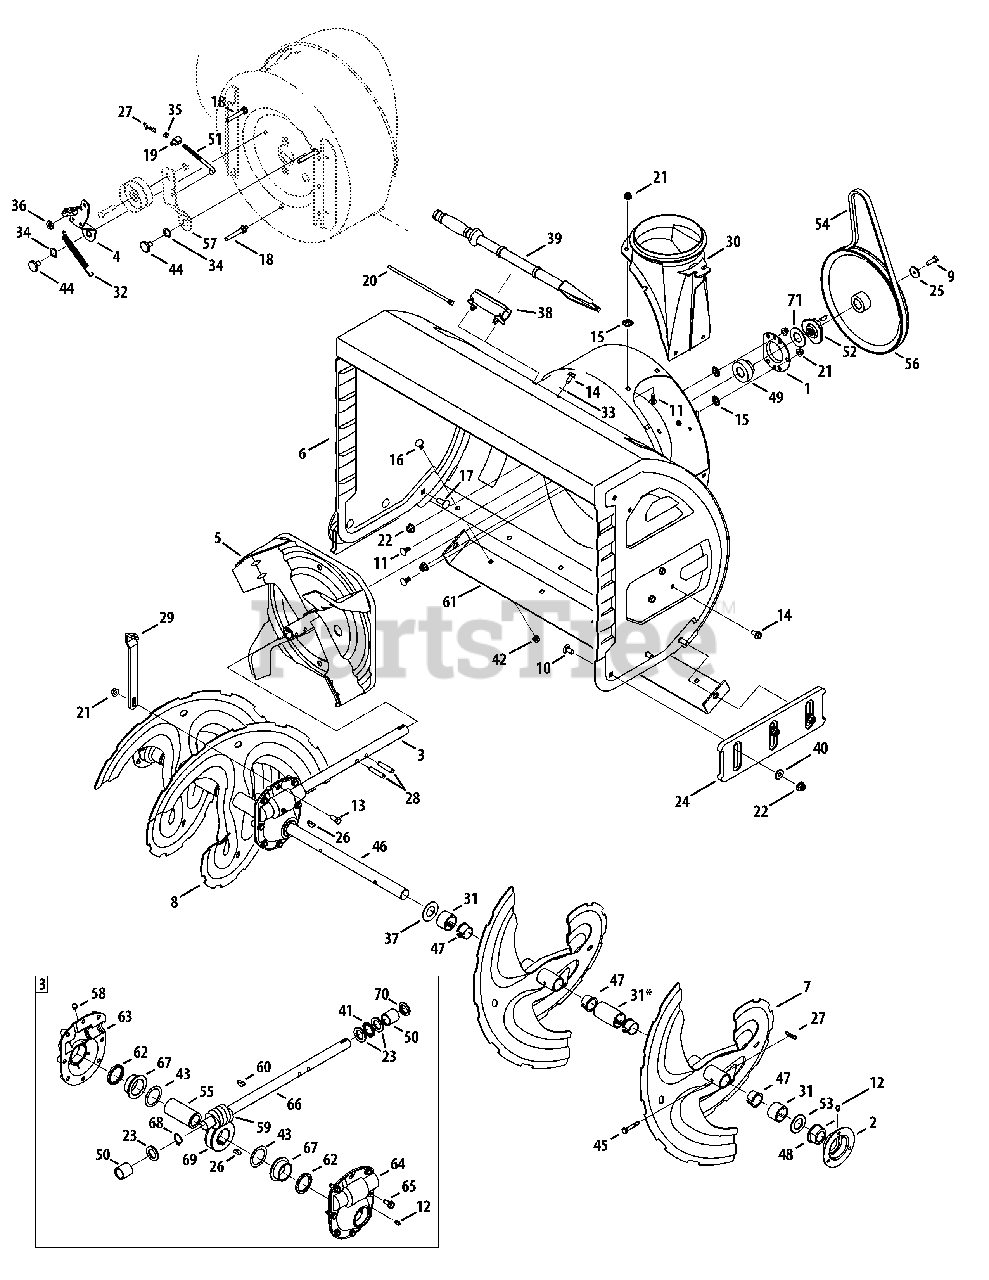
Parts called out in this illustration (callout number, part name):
1	Housing, Bearing
2	Housing, Bearing
3	Gear Box Assembly
4	Bracket Assembly, Auger Brake
5	Impeller, 16"
6	Housing, Auger - 30"
6	Housing, Auger - 33"
7	Spiral Assembly, LH
8	Spiral Assembly, RH
9	Screw, Hex Cap Lock, 5/16-24
10	Screw, Carriage, 3/8-16 x 1.00
11	Screw, Carriage, 5/16-18 x .75
12	Fitting, Lube
13	Screw, Hex Cap, 5/16-18 x 1.0 Gr5
14	Screw, 5/16-18 x .750
15	Nut, Push
16	Screw, Carriage, 5/16-18 x .75
17	Screw, Carriage, 3/8-16 x 1.25
18	Screw w/Stud, 5/16-18 x .4300
20	Tie Strap
21	Nut, Hex Flange Lock, 5/16-18
22	Nut, Hex Flange Lock, 3/8-16
23	Wash, Flat, .88 ID x .38 OD
24	Shoe, Skid, Deluxe
25	Washer, Flat, .34 x 1.5 x .15 Ht.
26	Key, Woodruff, 1/4 x 3/4
27	Pin, Bow-tie Cotter
28	Pin, Spiral, 5/16 x 1.75
29	Bracket, Gear Box Support
30	Adapter, Chute, 6"
31	Spacer, 1.0 x 1.5 x 1.0 Lg - 30" ONLY
31	Spacer, 1.0 x 1.5 x 2.5 Lg - 33" ONLY
32	Spring, Extension
33	Washer, Flat, .349 x .879 .063
34	Washer, Wave, .625 x .885 x .015
35	Jam Nut, 5/16-18
36	Washer, .344 x .75 x .12
37	Washer, 1.01 x 1.86 x .06
38	Clip, Mounting
39	Tool, Clean-out
40	Wash, Flat, .385 x .870 x .092
41	Bearing, Thrust
42	Nut, Hex, 5/16-18 Stainless
43	Wash, Flat, 1.52ID x 2.0 OD
44	Screw, Shoulder, .625 x .17
45	Pin, Shear, .25 x 1.75
46	Shaft, Spiral, - 30" ONLY
46	Shaft, Spiral, - 33" ONLY
47	Bushing, Flange,
48	Bearing, Flange w/Flats
49	Bearing, Self Aligning
51	Rod, Auger Idler
52	Adapter, Pulley w/Pins
53	Spacer, 1.004 x 1.375 x .25
54	V-Belt, 1/2 x 42
55	Shaft, Gear, Worm
56	Pulley, Auger Drive, 10.0
57	Bracket, Auger Idler
59	Gear, Worm
60	Key, Hi Pro, 3/16 x 3/4
61	Plate, Shave, Stainless - 30" ONLY
61	Plate, Shave, Stainless - 33" ONLY
63	Hsg, Ass’y, Auger RH (Incl. Ref. 62 & 67)
64	Hsg, Ass’y, Auger LH (Incl. Ref. 62 & 67)
65	Screw, LD, 5/16-18 x .750
66	Shaft, Drive, Auger
67	Flange Bearing
68	External, Retaining, Ring
69	Gear, Worm, LH
70	Seal, Oil
71	Washer, Flat, .76 x 1.49 x .06
